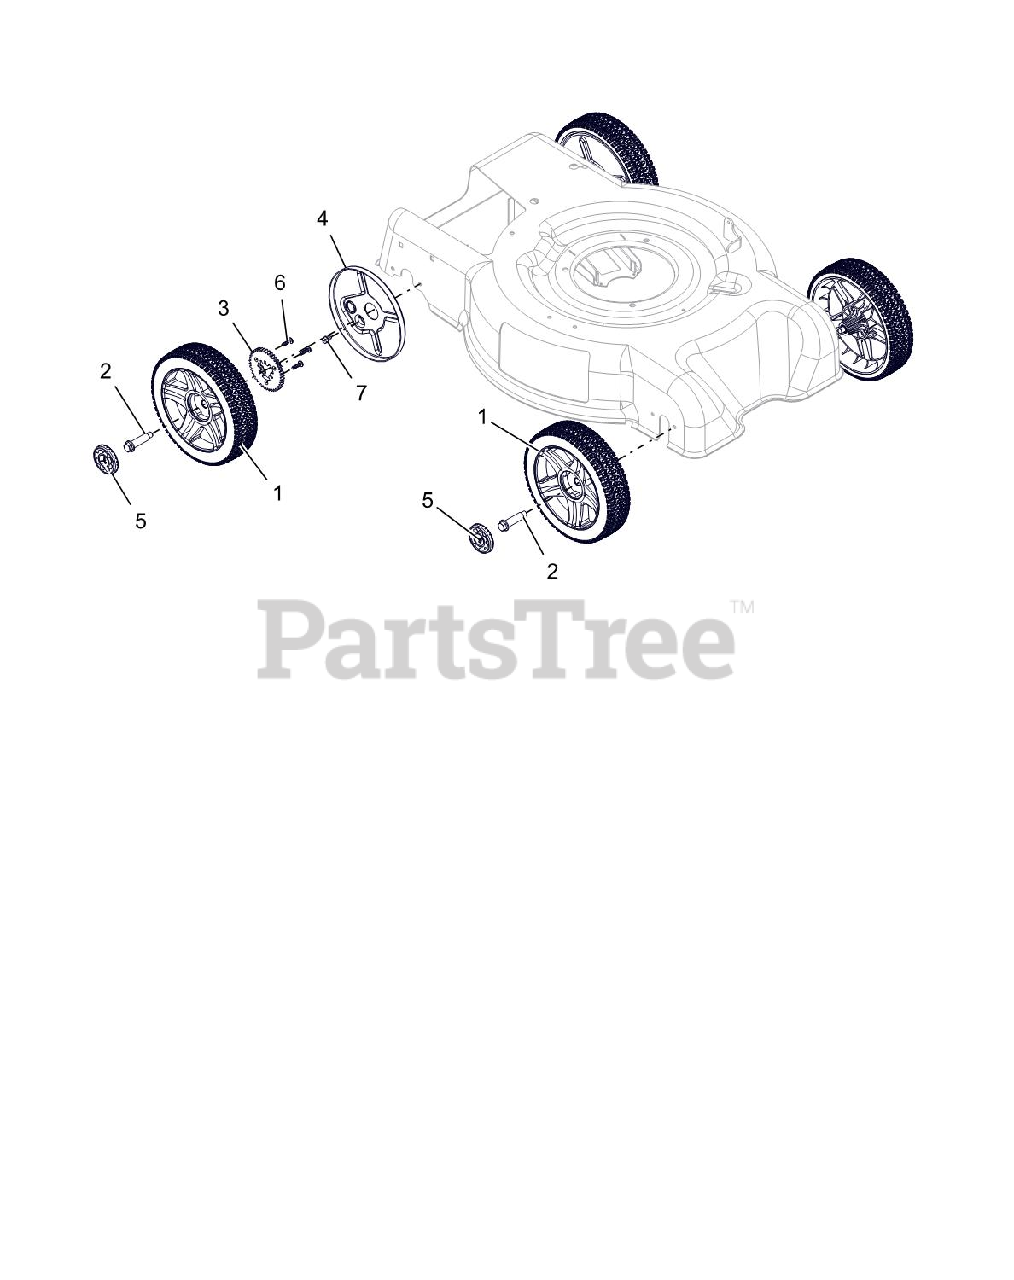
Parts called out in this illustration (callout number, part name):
1	ASSEMBLY, RAZOR WHEEL/BSHG
2	BOLT, WHEEL SHOULDER
3	GEAR, WHEEL
4	COVER, WHEEL
5	CAP, LM WHEEL HUB
6	SCR-TAP 12-14X.75PLSTITE @BLZC
7	@SCR-TAP .25-20X.37 HWH YWZ TR
